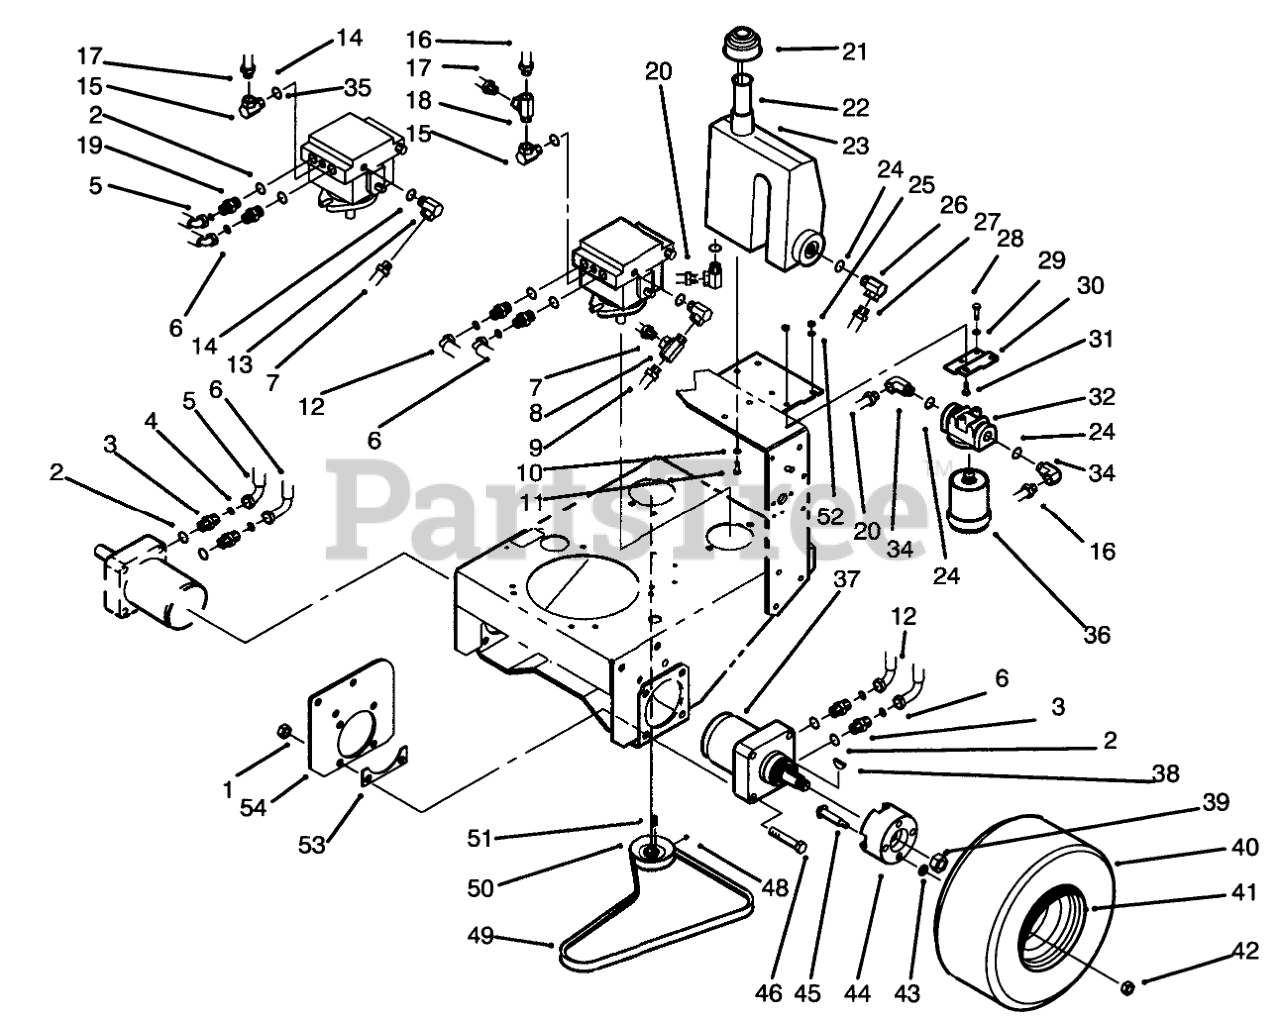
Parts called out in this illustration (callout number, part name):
1	NUT-LOCK, NI
2	O-RING
3	FITTING-STRAIGHT
4	O-RING
5	HYDRAULIC HOSE ASM
6	HYDRAULIC HOSE ASM
7	HYD HOSE ASM
8	FITTING-HYD, TEE
9	HYDRAULIC HOSE ASM
10	WASHER-LOCK
11	SCREW-HH
12	HYDRAULIC HOSE ASM
13	FITTING-HYD, 90 DEG
14	O-RING
15	SWIVEL-PIPE, FEMALE
16	HYDRAULIC HOSE ASM
17	HYD HOSE ASM
18	FITTING-HYD, TEE
19	FITTING-STRAIGHT
20	HYD HOSE ASM
21	OIL CAP ASM
22	SCREEN-FILLER
23	Reservoir-Oil
24	O-RING
25	NUT-LOCK, NI
26	FITTING-HYD, 90 DEG
27	HYDRAULIC HOSE ASM
28	SCREW-HH
29	WASHER-LOCK
30	FILTER MOUNTING BRKTR
31	SCREW-HH
32	FILTER HD ASM
34	FITTING-HYD, 90 DEG
35	O-RING
36	CARTRIDGE-FILTER, OIL
37	WHEEL MOTOR ASM
38	KEY-WOODRUFF
39	Nut (Incl. w/Motor)
41	WHEEL
42	NUT-LUG
43	PUSHNUT
44	HUB-WHEEL
45	SCREW-HH
46	SCREW-HH
48	SCREW-SET
49	BELT-V
50	PUMP PULLEY
51	KEY-PUMP
52	WASHER-PLAIN
53	Spacer
54	Plate-Frame
